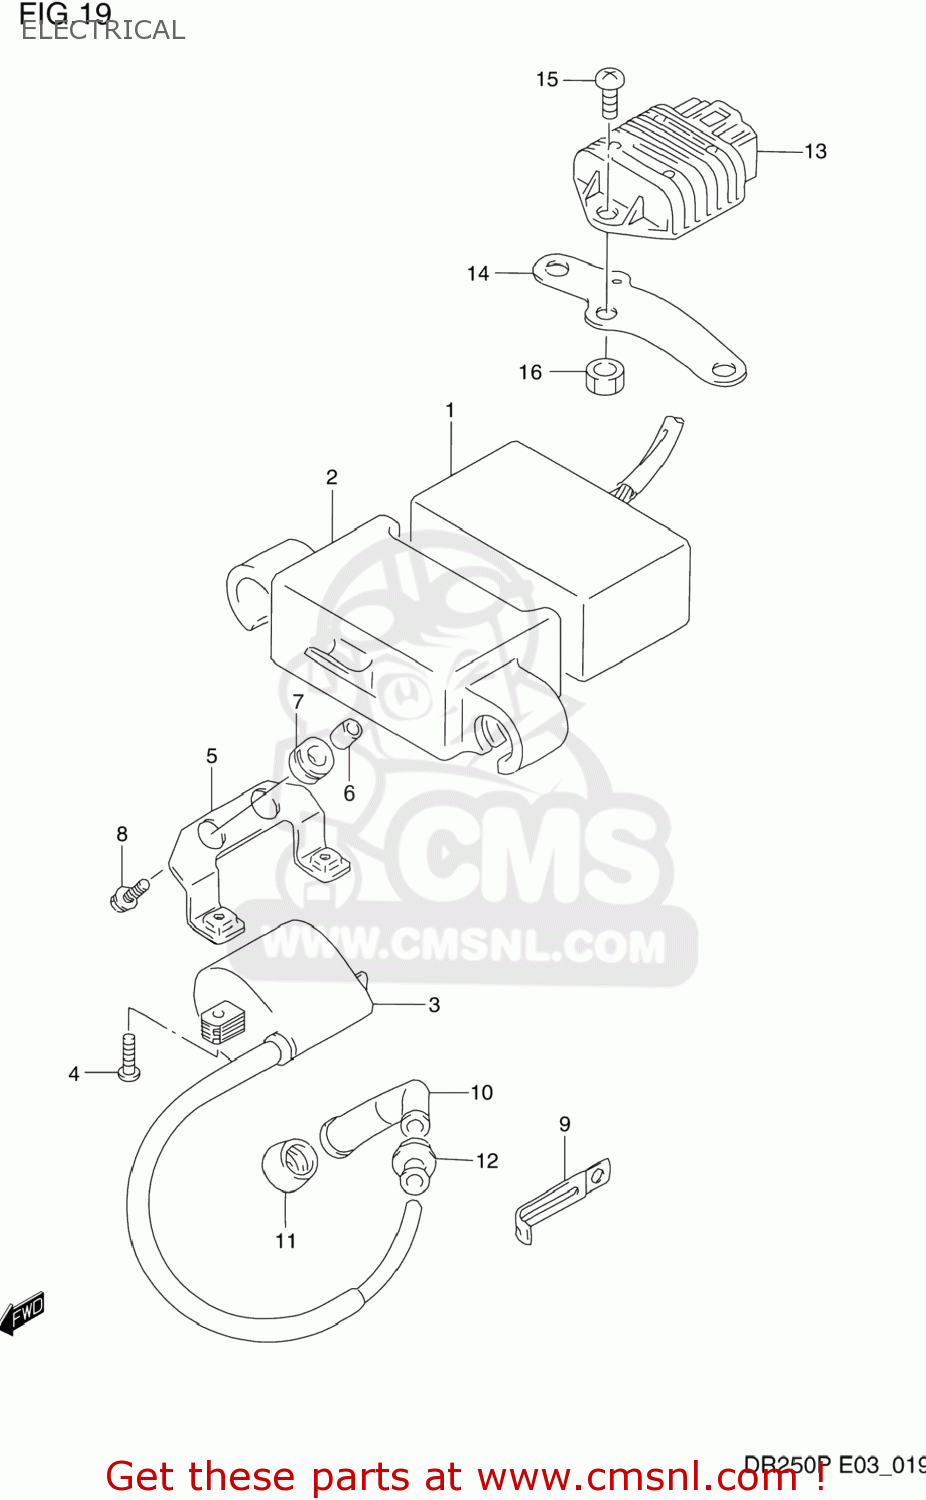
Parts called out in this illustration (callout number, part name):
1	CDI UNIT
2	CUSHION,CDI UNIT
3	COIL ASSY,IGNITION
4	SCREW
5	BRACKET,IGNITION COIL
6	SPACER (6.3X9.1X6.7)
7	CUSHION
8	BOLT
9	CLAMP
10	CAP,SPARK PLUG
11	SEAL,SPARK PLUG CAP
12	SEAL,HIGH TENSION CORD
13	REGULATOR ASSY
14	BRACKET,REGULATOR
15	SCREW
16	NUT
